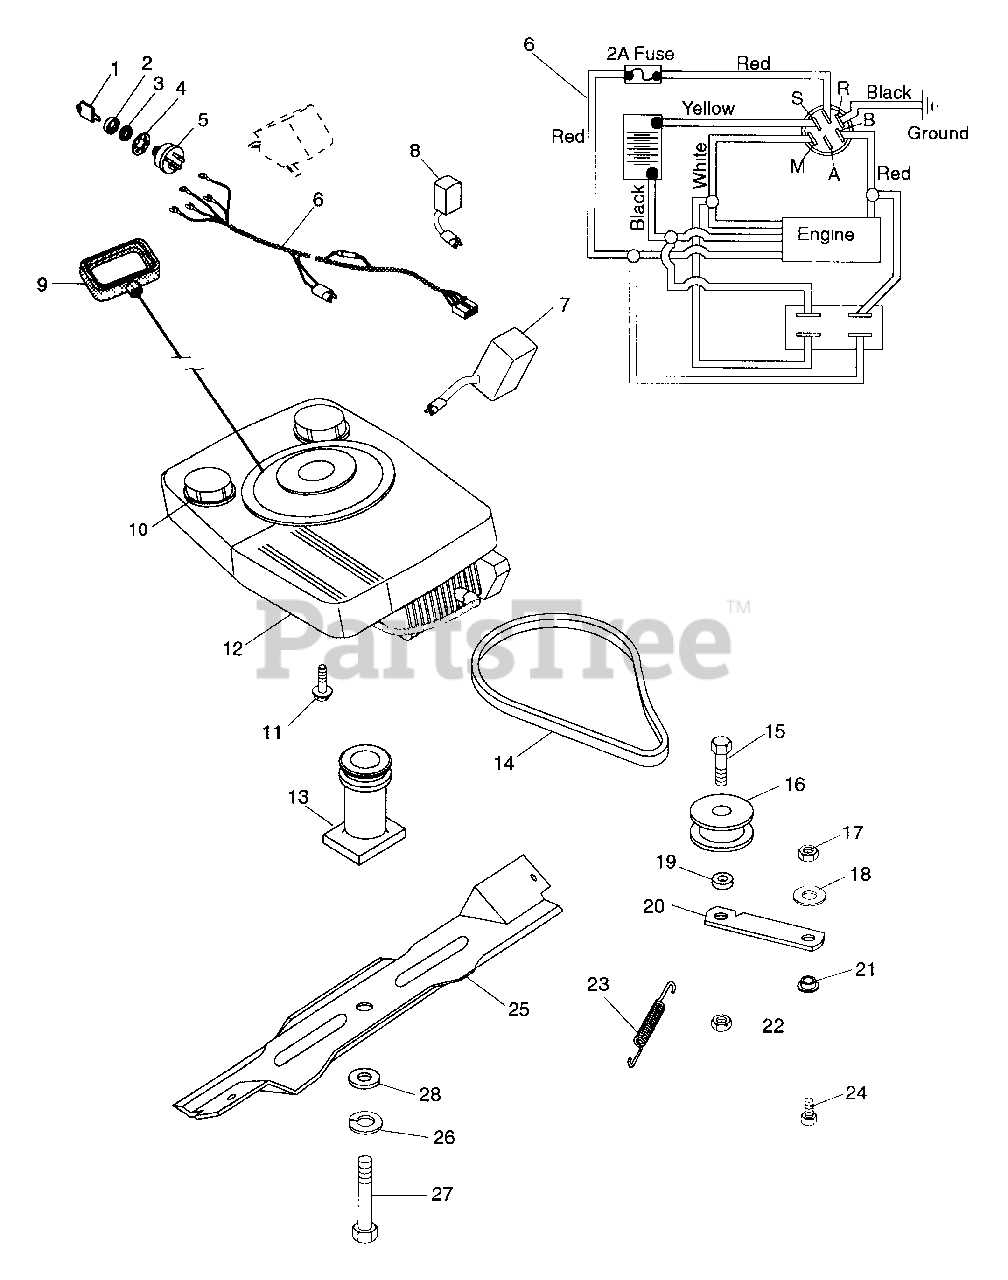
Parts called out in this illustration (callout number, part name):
1	KEY -W/CAP
2	CAP - IGNITION SWITCH
3	NUT-PANEL .625-32 GRECO
4	WSHR-LK-INT .625X.045 PL
5	KEY SWITCH
6	WIRE HARNESS
7	BATTERY
8	BATTERY CHARGER
9	HANDLE, RECOIL START
10	FUEL CAP
11	SCR-TAP .375-16X1.0 HWH PL TR
12	ENGINE TEC. 5 HP RECOIL VECTOR
12	ENGINE TEC 5.5HP RECOIL VECTOR
12	ENGINE TEC 5.5HP ELEC. VECTOR
12	ENGINE TEC. 4.5HP. RECL. PREM
12	ENGINE TEC. 6.0HP. ULTRA OHV
12	ENGINE TEC. 5.0HP. RECL. PREM
12	ENGINE B/S 5HP QUANTUM XTE
12	ENGINE B/S 5HP. REC QUAN. I/C
12	ENGINE TEC. 5HP RECOIL 2 CYCLE
13	BLADE ADAPTER
13	BLADE ADAPTER TECUMSEH
13	BLADE ADAPTER BRIGGS/STRATTON
14	V-BELT, 3L-COGGED
15	BLT-HEX .44-14X1.25 PL GR2
16	IDLER-FLAT 1.75 X .47
17	NUT-LK .312-18 GR A PL
18	WSHR-FL-STL .323X.625X.062 PL
19	SPACER .52 X .45 X .34
20	IDLER ARM
21	BSHG-FLG .325X.501X.250X1.120
22	NUT-LK .437-14 GR A PL
23	SG-TENS .043X.44X3.31 WLD 5.8
24	BLT-HEX .31-18X.75 PL GR2
25	21" MOWER BLADE
25	BLADE, LM 21" MULCHING
26	WSHR-LK .375X.094 MED PL
27	BLT-HEX .38-24X2.00 PL GR5
28	WSHR-HDND-THR .390X1.50X.125PL
28	KEY-WDRF .156X.625X.25 SAE 6
